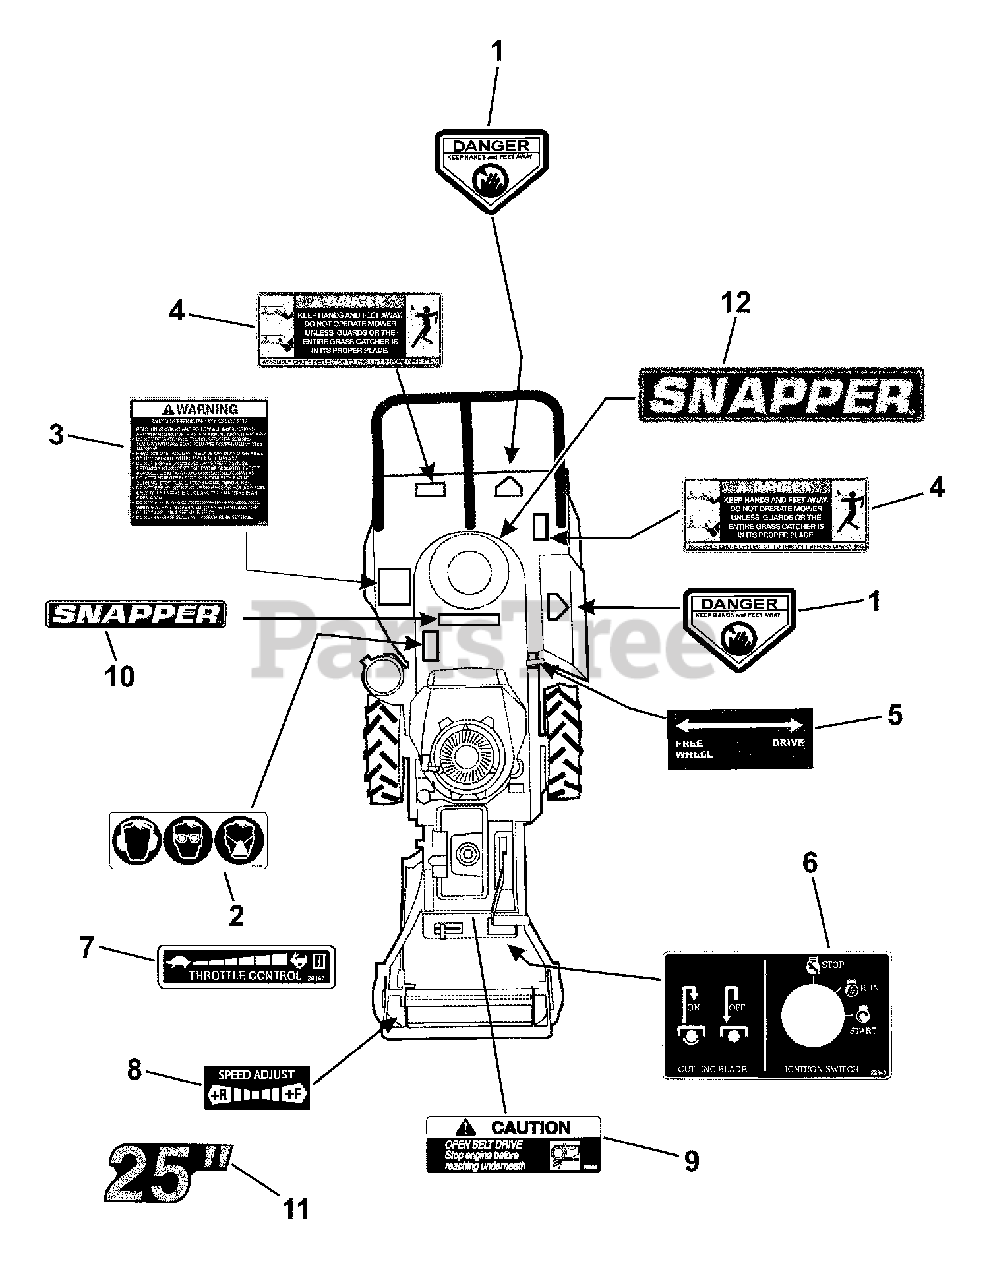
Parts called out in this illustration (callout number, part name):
1	DECAL, Danger, Cut Finger (CPSC)
2	DECAL, Personal Protection
3	DECAL, Warning, Brush Cutter
4	DECAL, Caution, Guard Catcher
5	DECAL, Transmission Drive
6	DECAL, Ignition/Cutting Blade
7	DECAL, Throttle, Brush Cutter
8	DECAL, Speed Adjuster
9	DECAL, Caution, Open Belt Drive
10	DECAL, SNAPPER, 8" long
11	DECAL, 25"
12	DECAL, SNAPPER, 14-1/2" long
12	DECAL, SIMPLICITY
